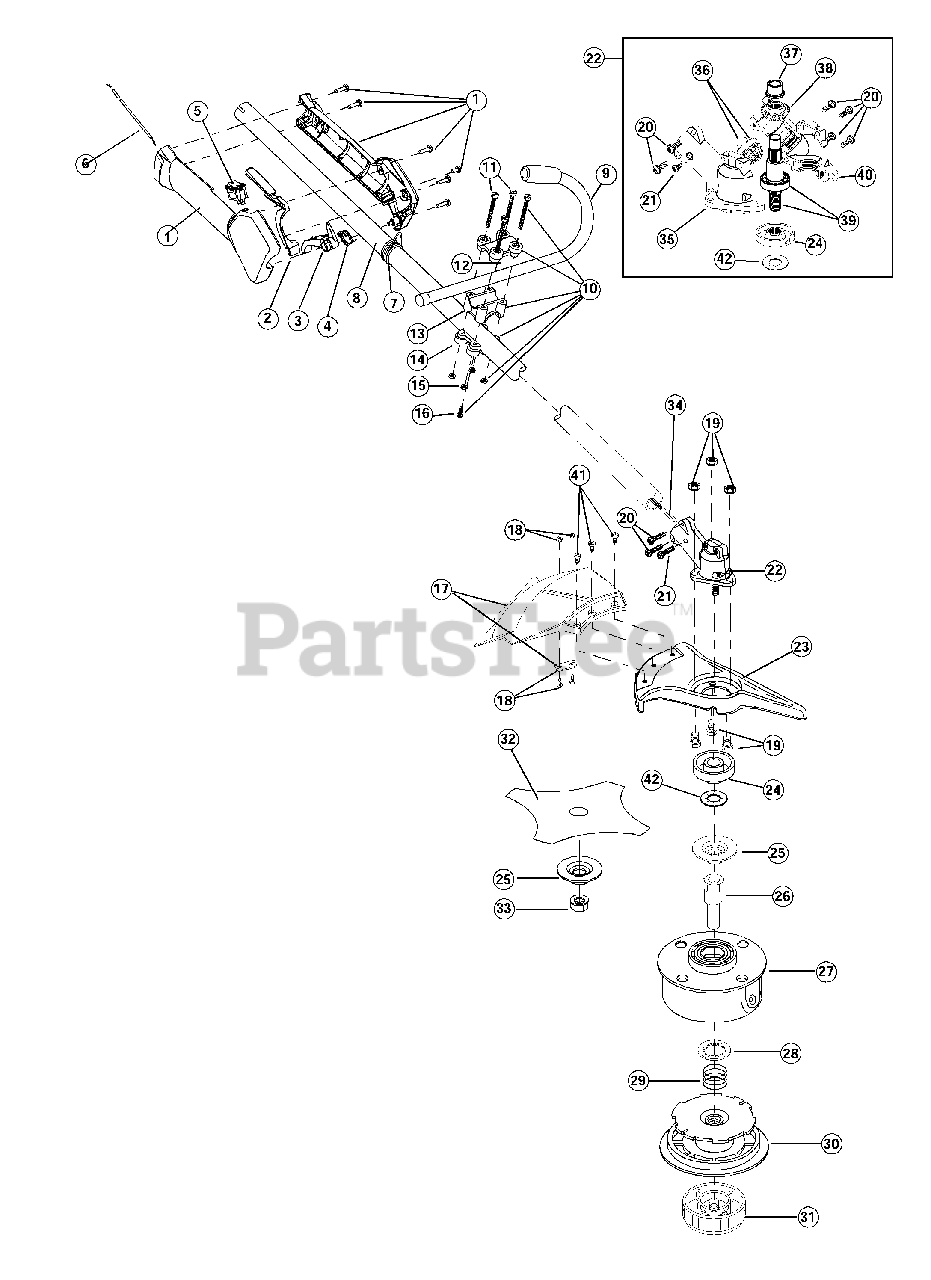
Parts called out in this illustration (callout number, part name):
1	Throttle Housing and Trigger Assembly
2	Throttle Trigger Lock-Out
3	Throttle Trigger
4	Throttle Trigger Spring
5	Switch Assembly
6	Throttle Cable Assembly
7	Harness Clip
8	Upper Drive Shaft Housing Assembly
9	J-Handle Assembly
10	Handle Bracket Assembly
12	Upper Handle Clamp
13	Middle Handle Clamp
14	Lower Handle Clamp
16	Anti-Rotation Screw
17	Shield and Blade Assembly
18	Blade Assembly
19	Shield Mount Screw Assembly
20	Gearbox Mounting Screw
21	Anti-Rotation Screw
22	Gearbox Assembly
23	Blade Shield
24	Blade Driver
25	Retaining Washer
26	Spool Shaft
27	Outer Spool and Eyelet Assembly
28	Retainer
29	Spring
30	Inner Reel
31	Bump Head Knob Assembly
32	4-Tooth Blade
33	Nut
34	Flexible Drive Shaft
35	Right Housing
36	Pinion Gear Assembly
37	Output Shaft Bushing
38	Output Shaft Gear
39	Output Shaft Assembly
40	Left Housing
41	Shield Mounting Screw
42	Palnut
